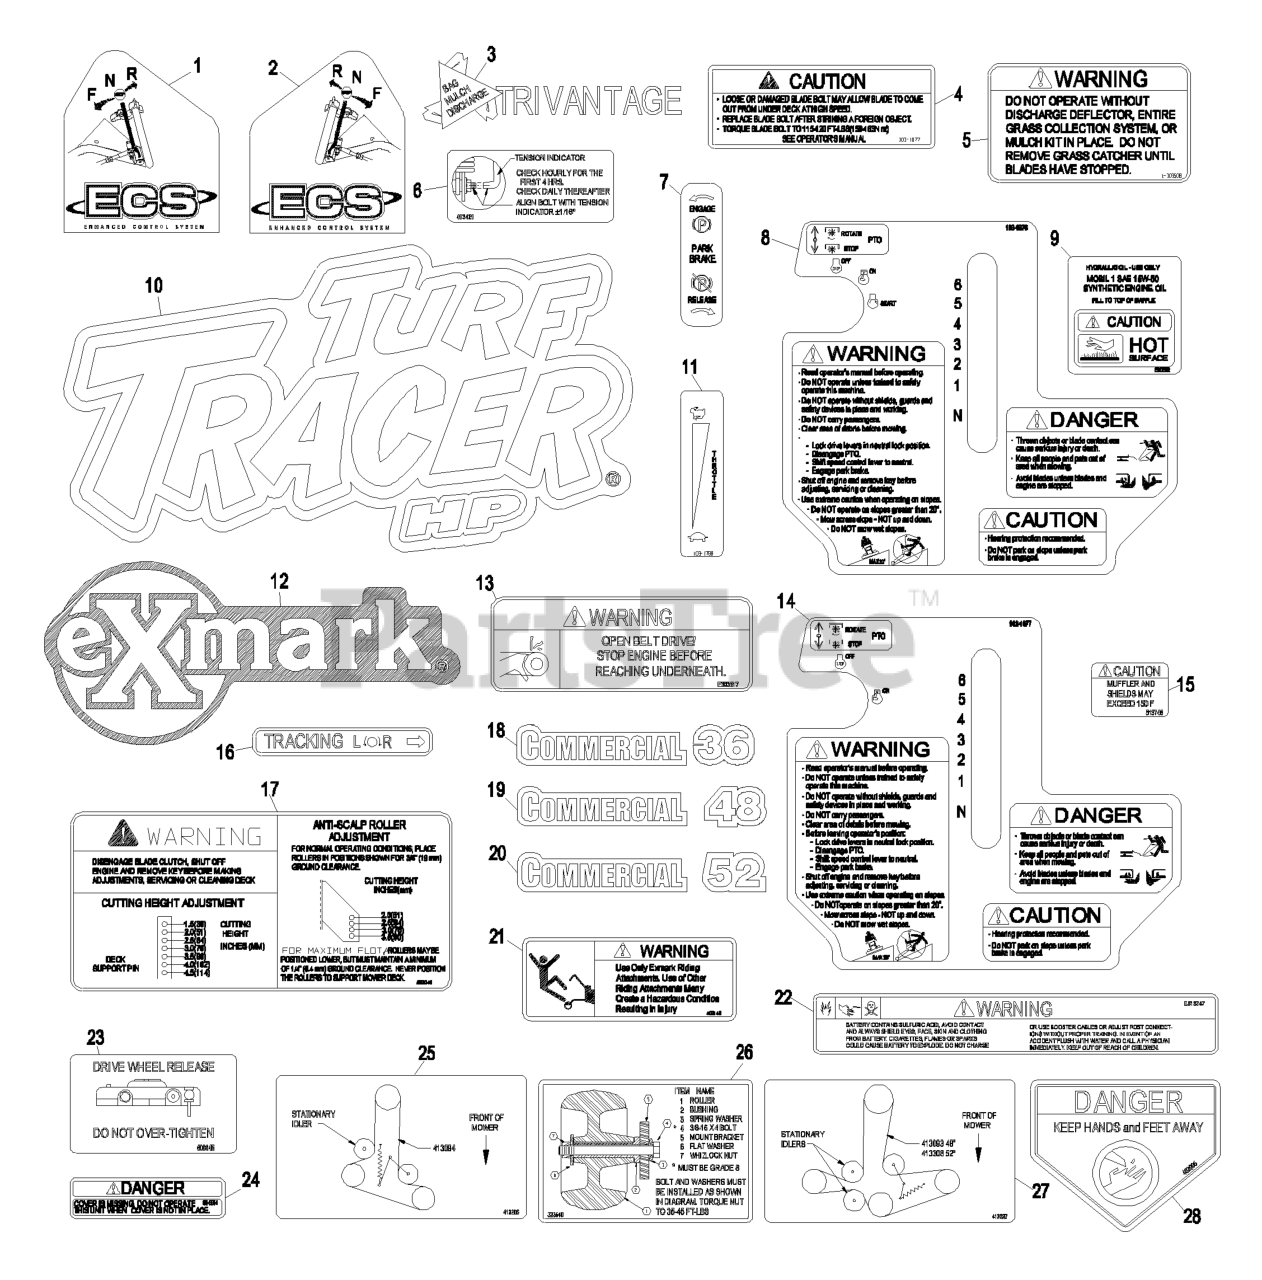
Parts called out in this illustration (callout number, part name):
1	DECAL,LH ECS INSTRUCTION
2	DECAL,RH ECS INSTRUCTION
4	DECAL,BOLT TORQUE
5	DECAL-WARNING, DISCHARGE
6	DECAL,INDICATOR
7	DECAL-BRAKE, PARK
8	DECAL,CONSOLE
10	DECAL,TTHP MODEL
11	DECAL,THROTTLE ONLY
13	DECAL,BELT DRIVE
14	DECAL,ECS CONSOLE
16	DECAL,TRACKING ADJUST
17	DECAL,ANTI SCALP
18	DECAL,COMMERCIAL 36
19	DECAL,COMMERCIAL 48
20	DECAL,COMMERCIAL 52
21	DECAL,SULKY WARNING
22	DECAL-BATTERY
23	DECAL,DRIVE RELEASE
24	DECAL-COVER, MISSING
25	DECAL,BELT ROUTING
26	DECAL,ROLLER MOUNTING
27	DECAL,BELT ROUTING
28	DECAL-DANGER
